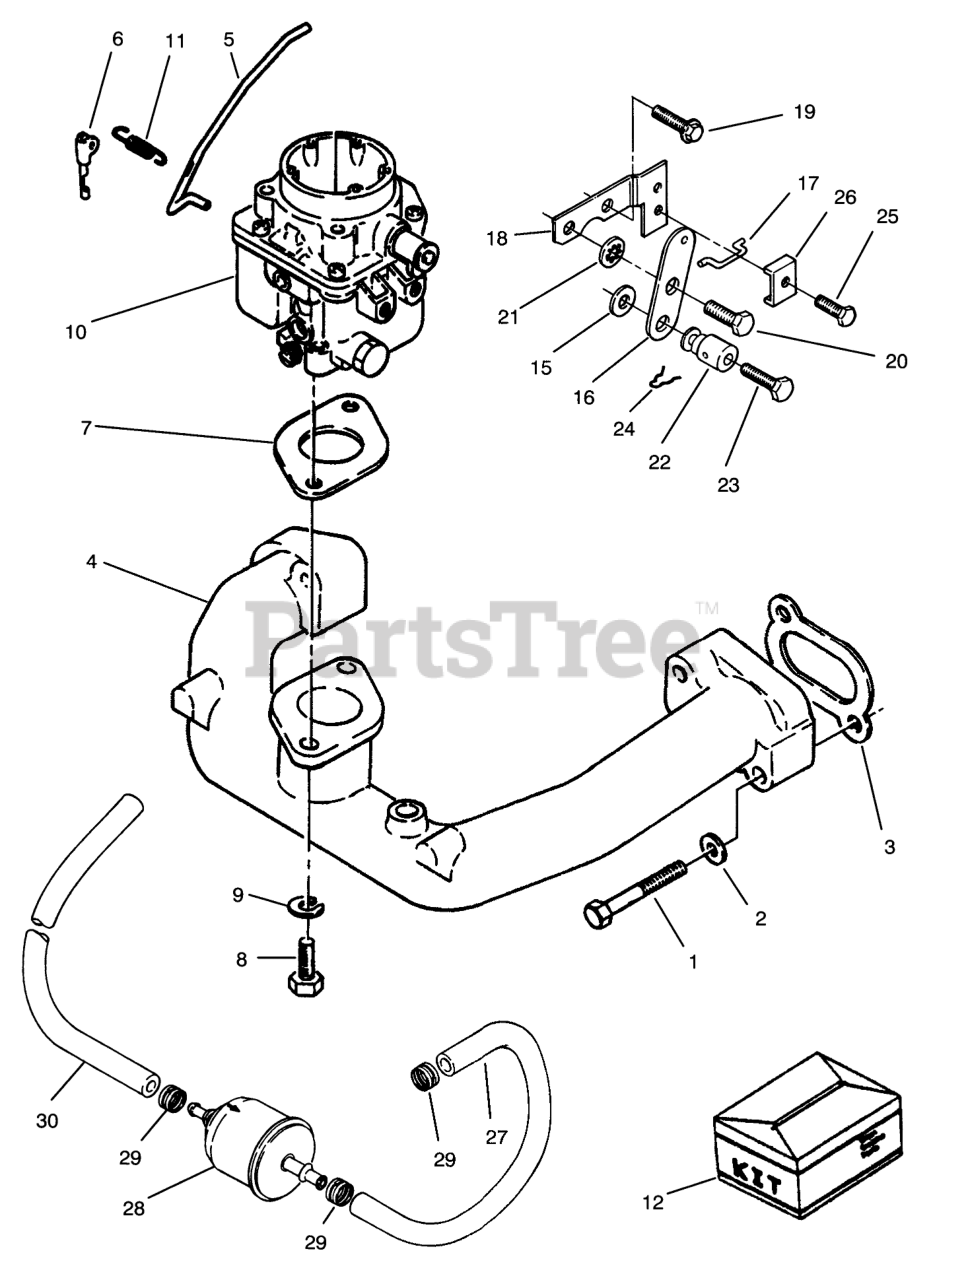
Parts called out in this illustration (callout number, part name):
2	Nut-M8
3	Gasket
4	INTAKE-MANIFOLD
5	GOVERNOR-CONTROL ROD
6	CONTROL-ROD CLIP
7	Gasket
8	HEX-HEAD CAP SCREW
9	Washer
10	COMPLETE-CARBURETOR
11	SPRING
12	Kit-Repair
15	Washer
16	SWIVEL-CHOKE
17	LINK-CHOKE
18	BRACKET
19	Bolt
20	BOLT-SHOULDER
21	Lockwasher
22	SWIVEL
23	Bolt
24	PIN-COTTER
25	Bolt
27	Hose
28	Filter-Fuel
29	Clamp
30	Hose
